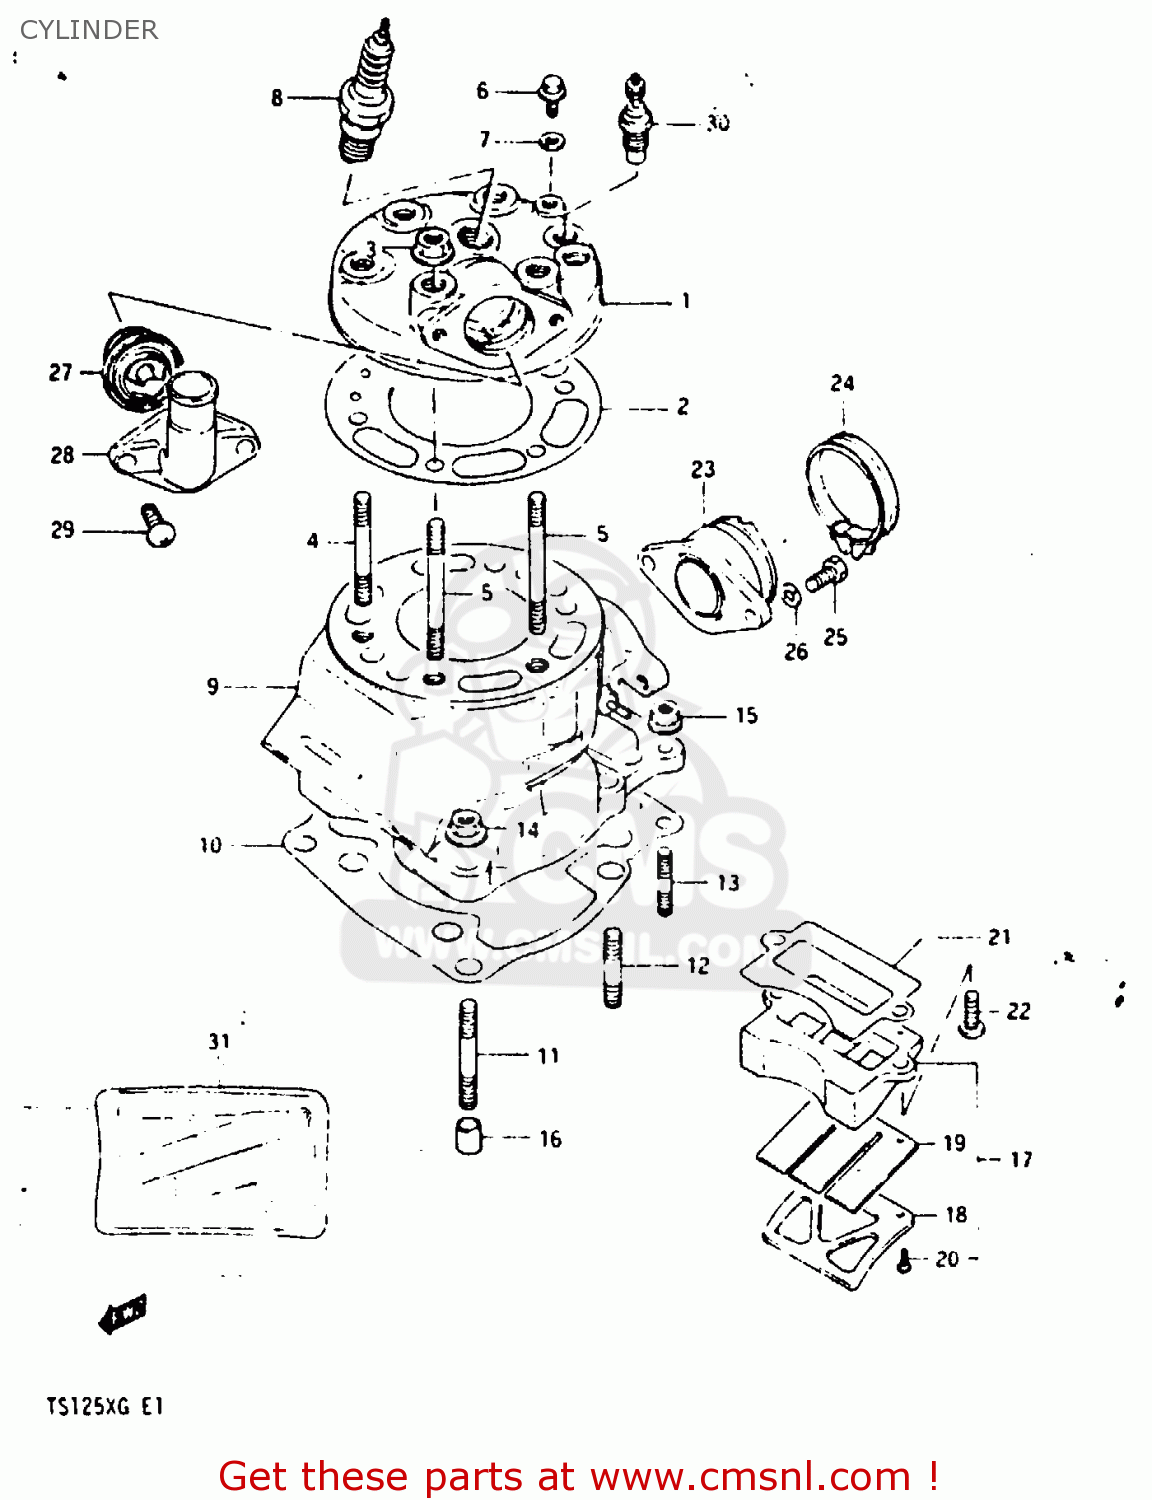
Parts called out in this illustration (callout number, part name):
1	CYLINDER HEAD
2	GASKET, CYLINDER HEAD
3	NUT 8MM
4	BOLT,STUD
5	STUD
6	UNION
7	GASKET(6.2X11X1).2 (NAS)
8	PLUG,SPARK
9	CYLINDER
10	GASKET, CYLINDER (MCA)
11	STUD
12	STUD
13	STUD BOLT L:20
14	NUT 8MM
15	NUT 6MM
16	PIN
17	VALVE ASSY, REED
18	STOPPER,REED VALVE
19	VALVE,REED
20	SCREW,REED VALVE
21	GASKET, REED VALVE (MCA)
22	SCREW
23	PIPE,INTAKE
24	CLAMP
25	BOLT 6X16
26	WASHER,LOCK
27	THERMOSTAT,WATER 65 DEG
28	COVER, THERMOSTAT
29	SCREW
30	GAUGE, WATER TEMP
31	GASKET SET (MCA)
